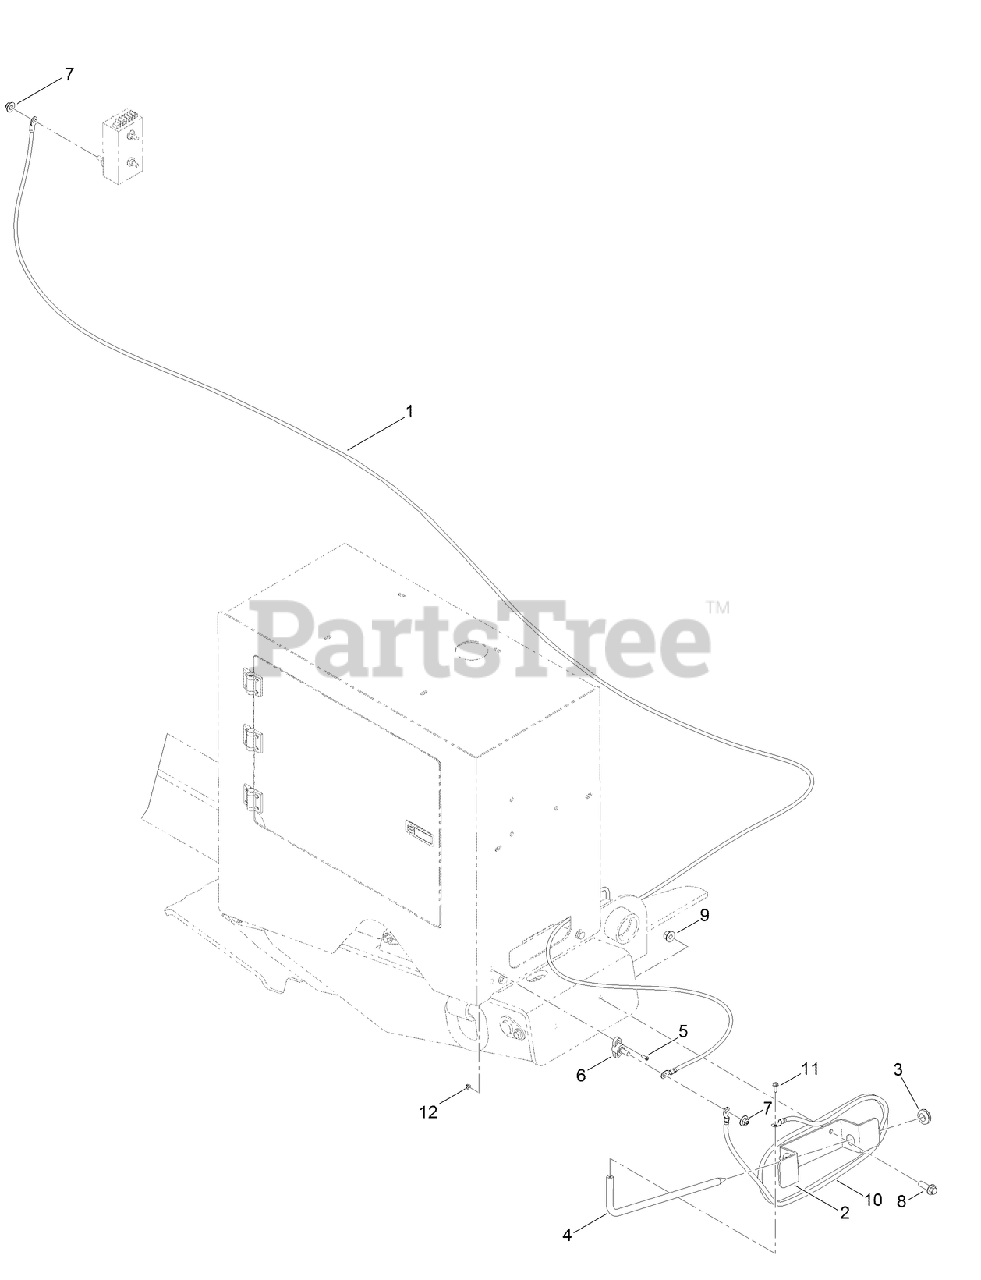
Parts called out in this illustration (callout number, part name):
1	CABLE-BATTERY, NEGATIVE
2	PLATE-HOLDER, STAKE
3	GROMMET
4	BAR-STAKE, GROUND
5	BLOCK-JUNCTION
6	SCREW-HSBH
7	NUT-FLANGE, NI
8	SCREW-HHF
9	NUT-LOCK, NI
10	CABLE-ALERT, STRIKE
11	SCREW-HHF
12	NUT-HHF, NY
